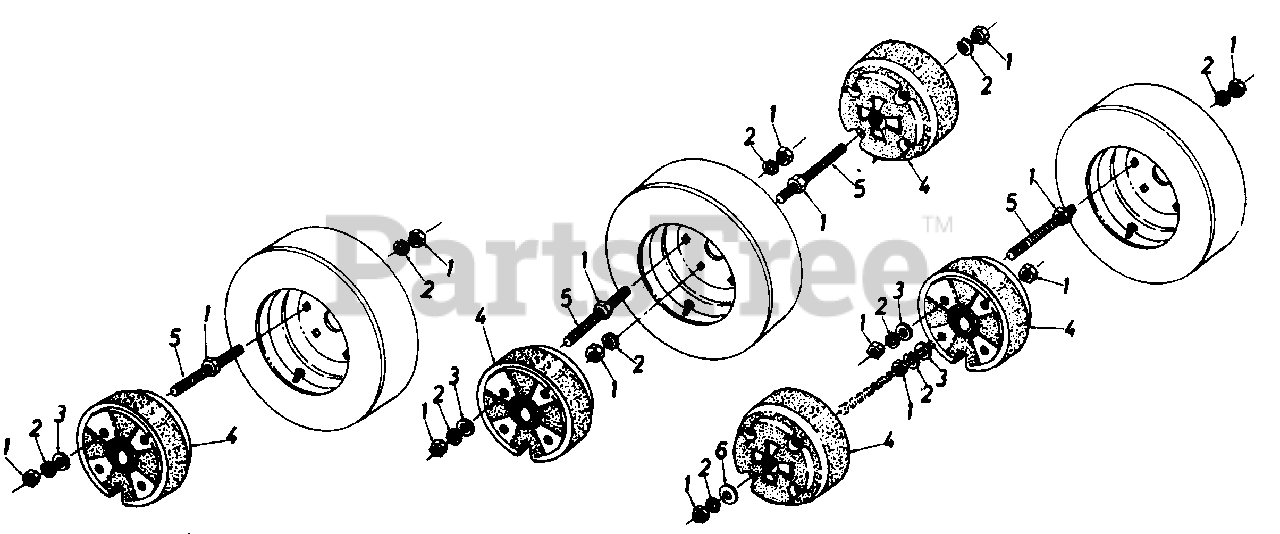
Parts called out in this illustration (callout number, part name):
1	Hex Nut 1/2-1 Thd.
2	LockWasher 1/2" I.D.
3	FlatWasher. 53" I.D. x.93" O.D.
4	Wheel Weight
5	Rod Threaded 1/2-13 x 9.50 Lg.
6	Fl.-Wash. .50" I.D. x 2.00" O.D.
